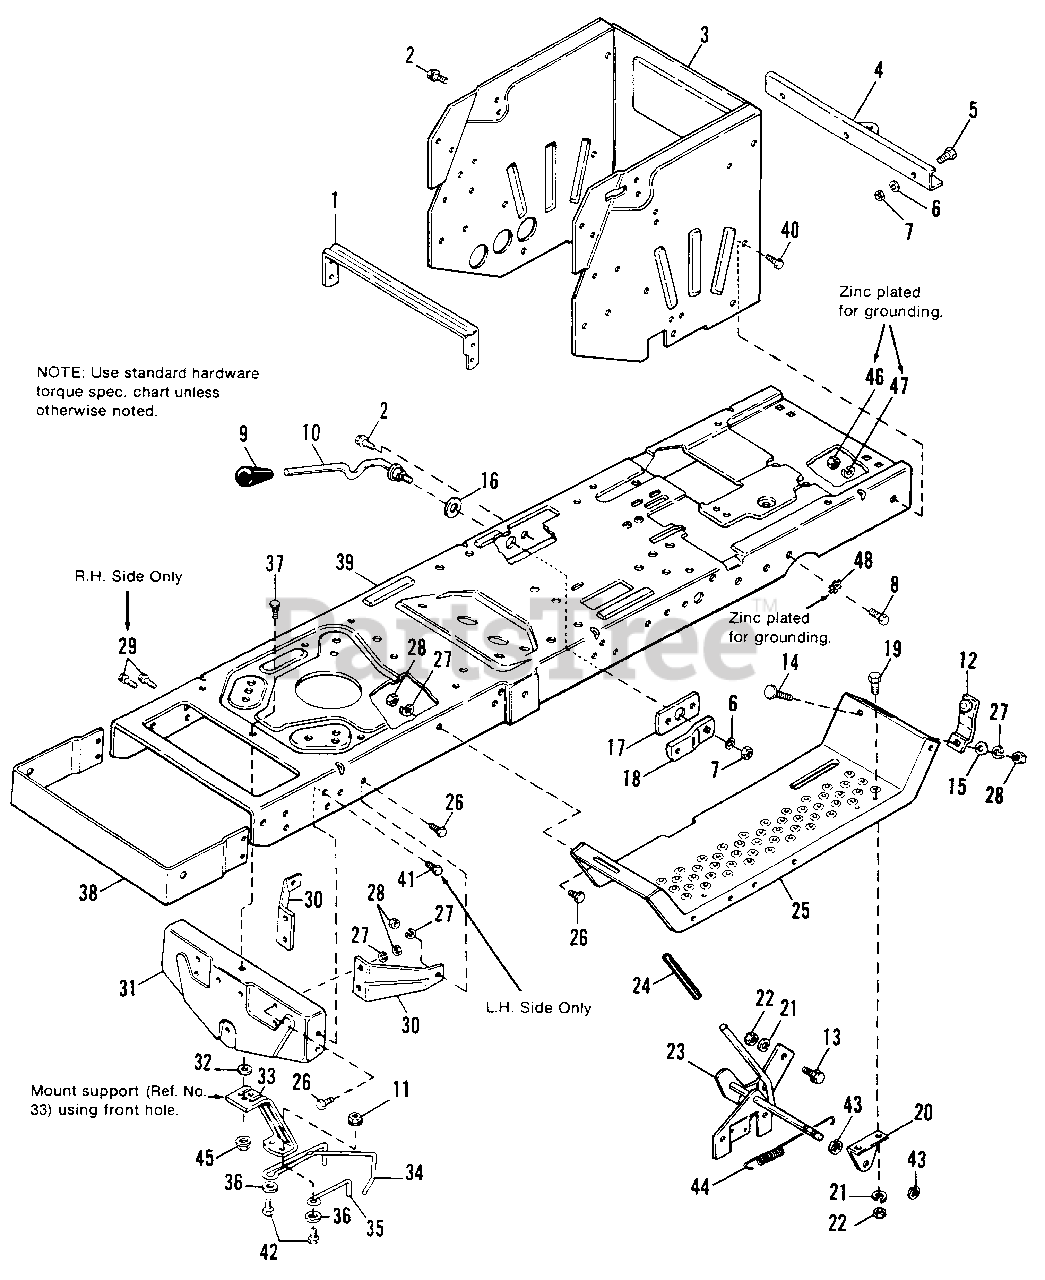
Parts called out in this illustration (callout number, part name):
1	BRACE, Seat
2	SCREW, Taptite, 5/16-18 x 1/2
3	SUPPORT, Axle Wrapper
4	BAR, Draw
5	CAPSCREW, Hex, 3/8-16 x 1, Gr. 5
6	LOCKWASHER, 3/8
7	NUT, Hex, 3/8- 16
8	CAPSCREW, Hex, 3/8-16 x 3/4
9	GRIP, Handle
10	HANDLE, Lift
11	NUT, Hex, Lock, Flange 5/16
12	LATCH ASSY.
13	SCREW, Taptite, 1/4-20 x 5/8
14	CARRIAGE BOLT, 5/16-18 x 3/4
15	WASHER, Plain, 5/16
16	WASHER, Nylon
17	BAR, Support
18	ARM, Support
19	CAPSCREW, Hex, 1/4-20 x 5/8, Gr. 5
20	SUPPORT, Clutch
21	LOCKWASHER, 1/4
22	NUT, Hex, 1/4-20
23	LEVER ASSY., Clutch
24	GRIP, Handle
26	CAPSCREW, Hex, 5/16-18 x 3/4
27	LOCKWASHER, 5/16
28	NUT, Hex, 5/16-18
29	SCREW, Taptite, 5/16-18 x 3/4
30	BRACE, Axle Support
31	SUPPORT, Axle
32	WASHER, Plain, 11/32-1 x 10 Ga.
36	WASHER, 1/4
37	CAPSCREW, Hex Flange Whizlock, 5/16-18 x 1-1/4
40	CAPSCREW, 3/8-16 x 1-1/2
41	SCREW, Taptite, 5/16-18 x 3/4
42	CAPSCREW, 5/16-18 x 7/8
43	RING, Retaining, 1/2
44	SPRING, Extension
45	NUT, Hex, Flange, Whizlock, 5/16-18
46	NUT, Hex, 3/8-16 (Zinc Pltd.)
47	LOCKWASHER, 3/8 (Zinc Pltd.)
48	LOCKWASHER, Ext. 3/8 (Zinc Pltd.)
